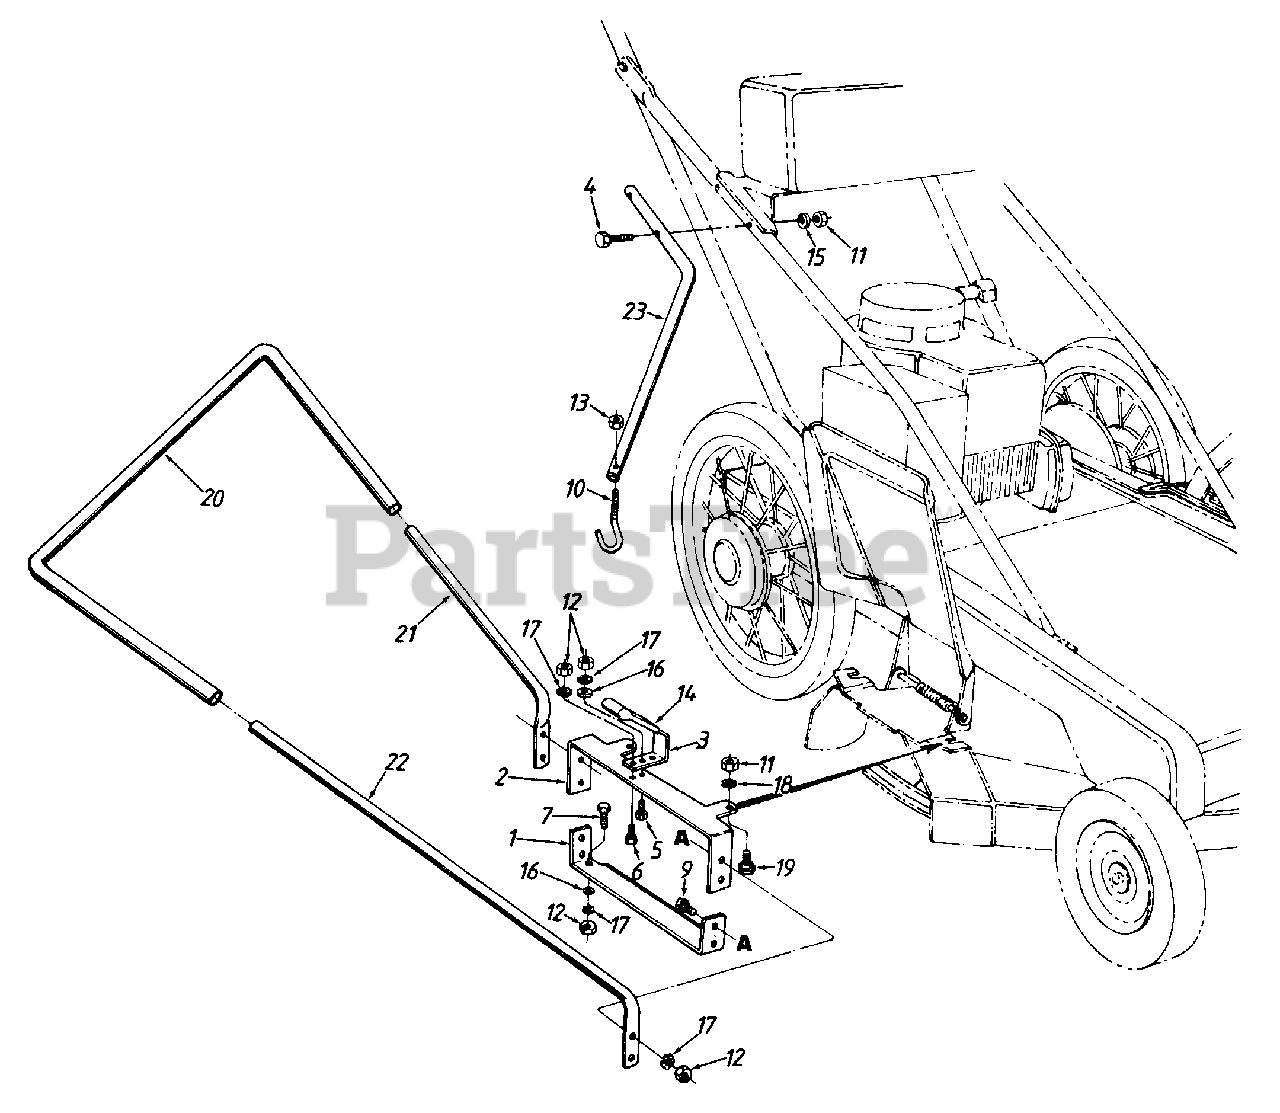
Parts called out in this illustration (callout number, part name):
1	Lower Opening Support
2	Upper Opening Support
5	Hex Bolt 1/4-20 x .35n Lg.
6	Hex Bolt 1/4-20 x .62" Lg.
7	Hex Bolt 1/4-20 x .5" Lg.
9	Hex Bolt 1/4-20 x 1.25" Lg.
11	Hex Nut 5/16-18 Thd.
12	Hex Nut 1/4-20 Thd.
13	Hex Ins. Nut 1/4-20 Thd.
15	L-Wash. 5/16" I.D. 2
16	Fl-Wash. .281" I.D. x .5" O.D. 3
17	Ext. L-Wash. 1/4" I.D. 8
18	Ext. L-Wash. 5/16" I.D. 2
19	Shoulder Bolt 2
20	Upper Frame
21	Lower Frame
22	Lower Frame Arm
23	Holding Arm
